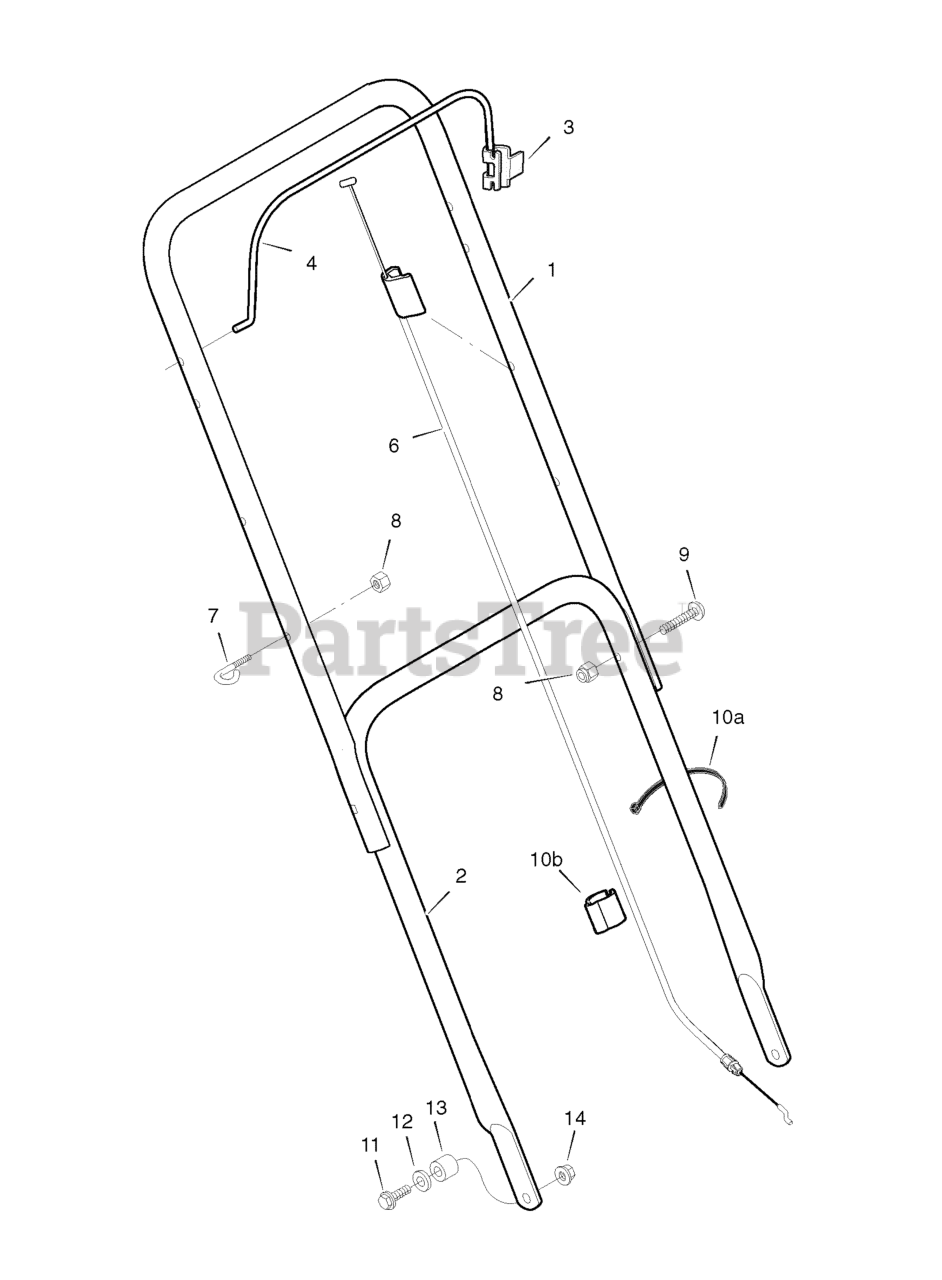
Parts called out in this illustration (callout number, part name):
1	HANDLE, UPPER 20 SD PUSH
2	HANDLE, LOWER 20
3	BRACKET, STOP LEVER
4	LEVER, STOP 20RB PUSH
6	CABLE, STOP, 43.50 20PNFCLX LH
7	GUIDE, ROPE
8	NUT, HEX LOCK 1/4-20 BZ
9	RHMS 1/4-20 X 1.375 BZ
11	BOLT, HEX, 3/8-16 UNC X 1.50 BRIGHT ZINC
12	WASHER, FLAT.390X1.25X.119Z
13	SPACER, HANDLE
14	NUT, HEX FLANGE, 3/8-16 NC
